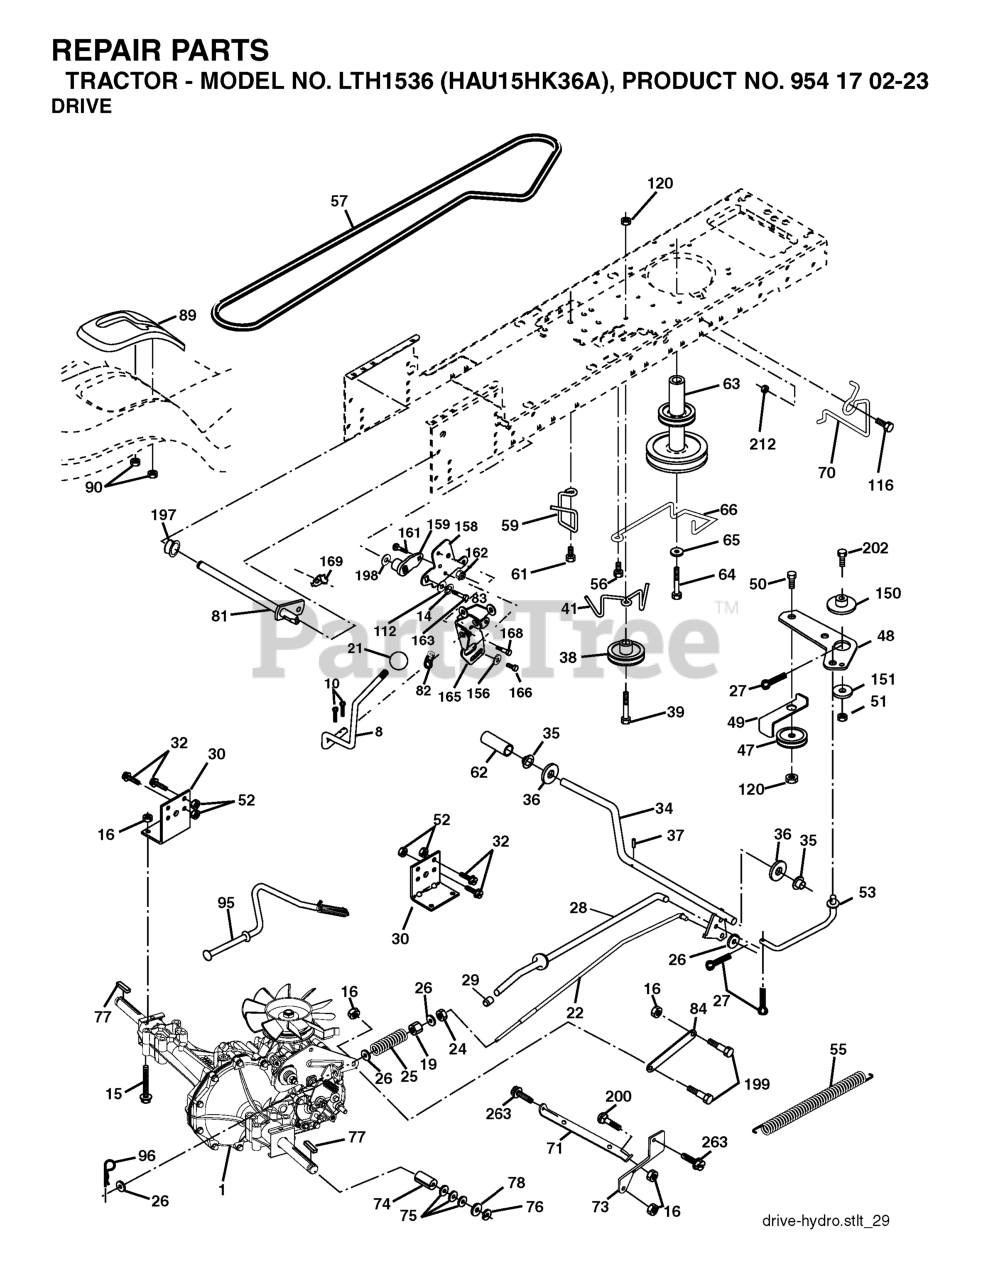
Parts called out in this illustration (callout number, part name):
8	ROD SHIFT FENDER ADJUST STLT
10	PIN COTTER
14	LOCKWASHER
15	BOLT HEX 5/16-18 GR 5
16	NUT.71038.31-18.HEX.NYLOCK
19	NUT
21	KNOB.DUCKHEAD.1/2
22	ROD BRAKE HYDRO
24	NUT
25	SPRING ROD LT
26	WASHER
27	COTTER PIN
28	ROD, PARKING BRAKE
29	PLUNGER CAP
30	BRKT, MOUNT TRNSAXLE
32	BOLT
34	SHAFT, FOOT PEDAL
35	BEARING.NYLON
37	DRIVE PIN
38	PULLEY IDLER COMPOSITE
41	KEEPER, BELT IDLER
47	IDLER PULLEY
48	BELLCRANK, CLUTCH
49	RETAIN BELT
50	BOLT.3/8-16X1.50
52	LOCKNUT
53	LINK, CLUTCH LT
55	SPRING, RETURN LT
56	SCREW.3/8-16
57	DRIVE BELT, LTH & YTH TRACTORS
59	KEEPER, BELT CENTER
61	SCREW 3/8-16X.875
62	PEDAL COVER T
63	ENGINE PULLEY
64	BOLT HEX 7/16-20X4-1/4"
65	LOCKWASHER
66	KEEPER BELT ENGINE
70	KEEPER BELT ENG
71	STRAP TORQUE LH HYDRO
73	STRAP TORQUE RH HYDRO
74	SPACER AXLE
77	SQUARE KEY
81	SHAFT ASM CROSS TAPERED
82	SHIFT SPRING
83	WASHER
84	LINK TRANSAXLE
89	SHIFT CONSOLE
90	NUT.PUSH.3/16
95	CONTROL ASM. BYPASS HYDRO
96	RETAINER M
103	NUT.HEX.1/2-20
116	BOLT D
120	NUT LOCK FLG 3/8-16 UNC
150	SPACER, RETAINER
151	WASHER 12/32X2X10GA
156	WASHER.SRRTD.5/16
158	BRACKET
159	RB HUB.SHIFT
161	BOLT
162	NUT.CROWNLOCK.1/4
165	RP BRACKET
166	CAPSCREW.HXHD.FLG.5/16-18X.625
168	BOLT.SHOULDER.5/16-18X
169	PLATE.FASTENING.CROSS.SHAFT
197	NYLINER SNAP 5/8" ID
198	WASHER.NYL.7/8IDX.105"HYD CR
199	BOLT SHOULDER 5/16-18 UNC
205	WASHER
212	NUT
263	SCREW, 3/8-16X3/4
